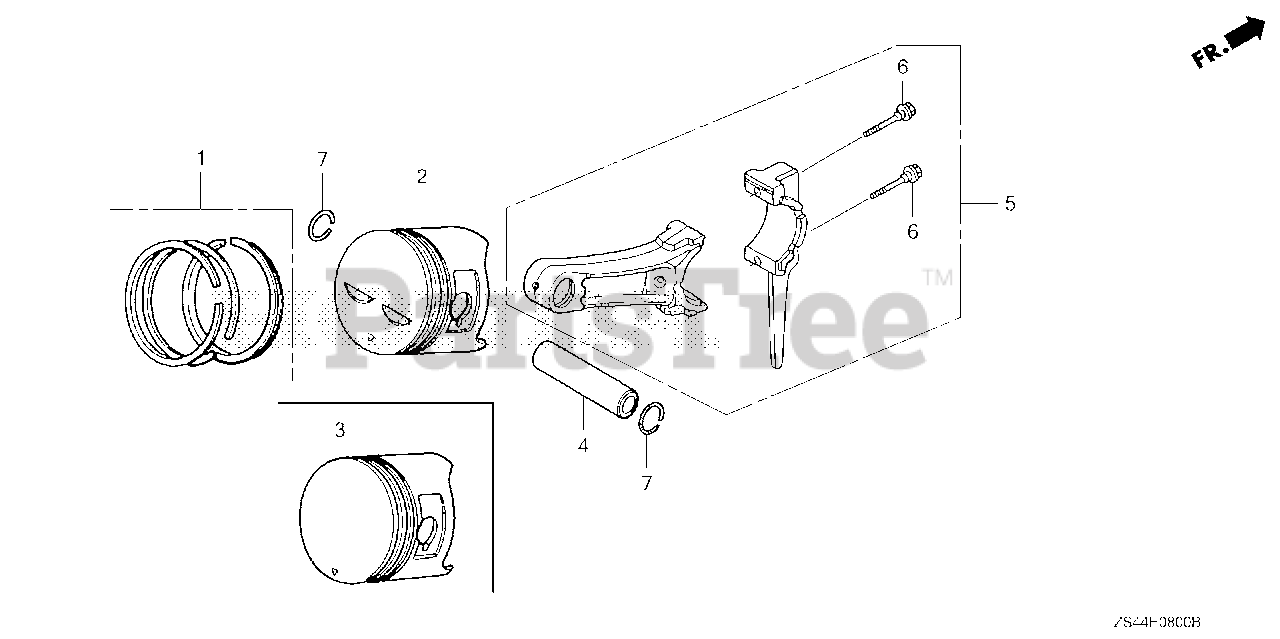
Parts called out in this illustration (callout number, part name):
1	RING SET, PISTON (STD) (NIPPON)
1	RING SET, PISTON (STD) (TEIKOKU)
1	RING SET, PISTON (0.25) (NIPPON)
1	RING SET, PISTON (0.25) (TEIKOKU)
1	RING SET, PISTON (0.50) (NIPPON)
1	RING SET, PISTON (0.50) (TEIKOKU)
1	RING SET, PISTON (0.75) (NIPPON) (NOT AVAILABLE)
1	RING SET, PISTON (0.75) (TEIKOKU)
1	RING SET, PISTON (0.75) (NIPPON)
2	PISTON (STD)
2	PISTON (0.25)
2	PISTON (0.50)
2	PISTON (0.75)
4	PIN, PISTON
5	ROD ASSY., CONNECTING (STD)
6	BOLT, CONNECTING ROD
7	CLIP, PISTON PIN (18MM)
